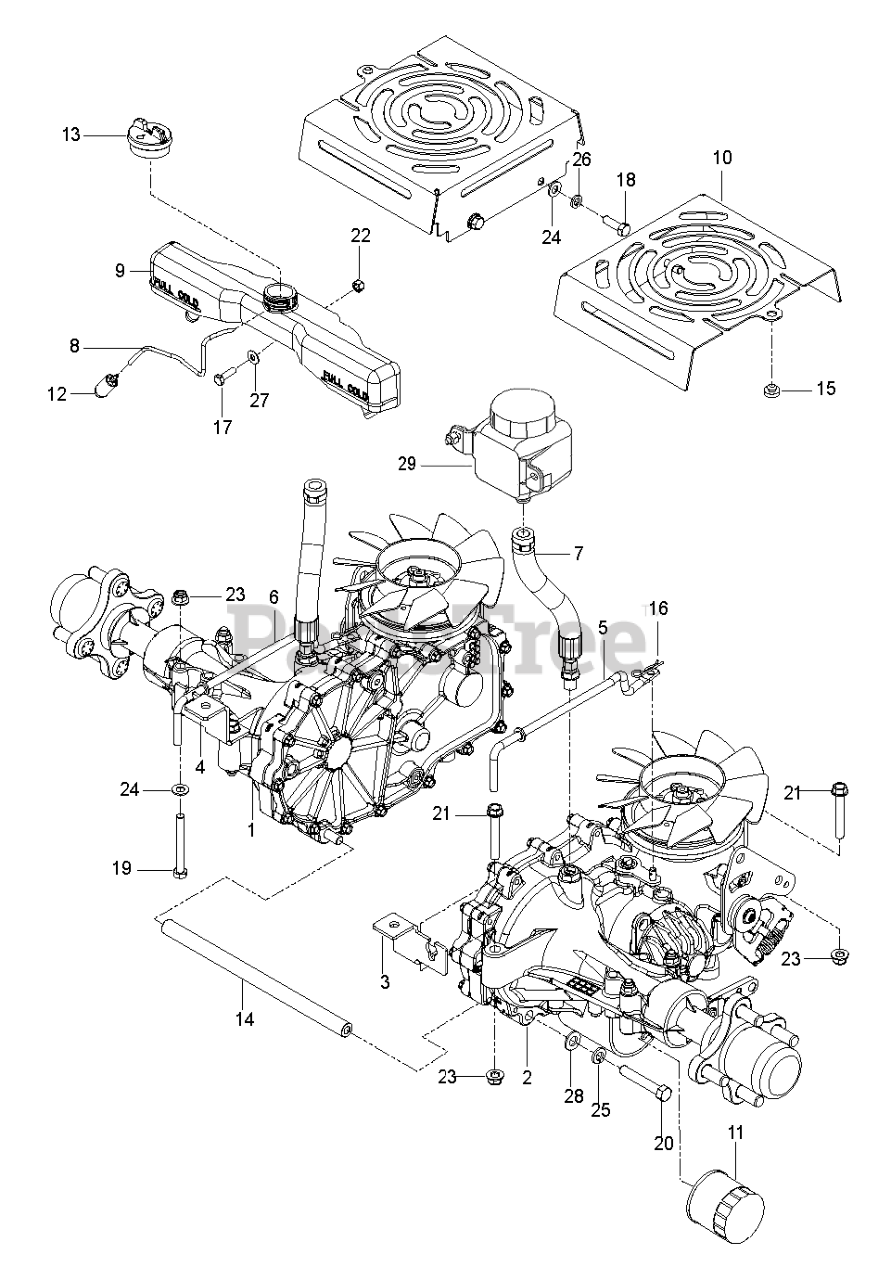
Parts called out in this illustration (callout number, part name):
1	HG_TRANS, ZT-3400, RT
2	HG_TRANS, ZT-3400, LT
3	BRACKET TRANS, RT BLACK MS-431
4	BRACKET TRANS, LT BLACK MS-431
5	LINKAGE, LEFT BYPASS
6	LINKAGE, RIGHT BYPASS
7	HOSE ASSY, EXPANSION
9	TANK EXPANSION W/CAP
10	SHIELD, FAN, BLK
10	SHIELD FAN BLACK
11	HG_FILTER, ZT4800 52114
12	FUEL PICK-UP ASSY
13	CAP EXPANSION W/SEAL
14	TUBE, SPACER, 3400
15	GROMMET, BUMPER
16	HAIRPIN #2
17	HCS 1/4-20X7/8 GR5
18	HCS 5/16C X 1
19	HCS 5/16C X 2-3/4
19	BOLT HEX
20	HCS 3/8-16X2-1/4 LOC PATCH GR8
21	HHFS 5/16-18 X 2.25 GD 5
22	NUT.1/4-20.HEX.NYLOC.ZD
23	5/16-18 NYLOC FLANGE NUT
24	WASHER
25	SLW 3/8 STD
26	WASHER.LOCK.HVY.HLCL.SPR.5/16
27	WASHER 1/4 SAE
28	WASHER 3/8 SAE FLAT
29	TANK.EXPANSION.350ML 71328
